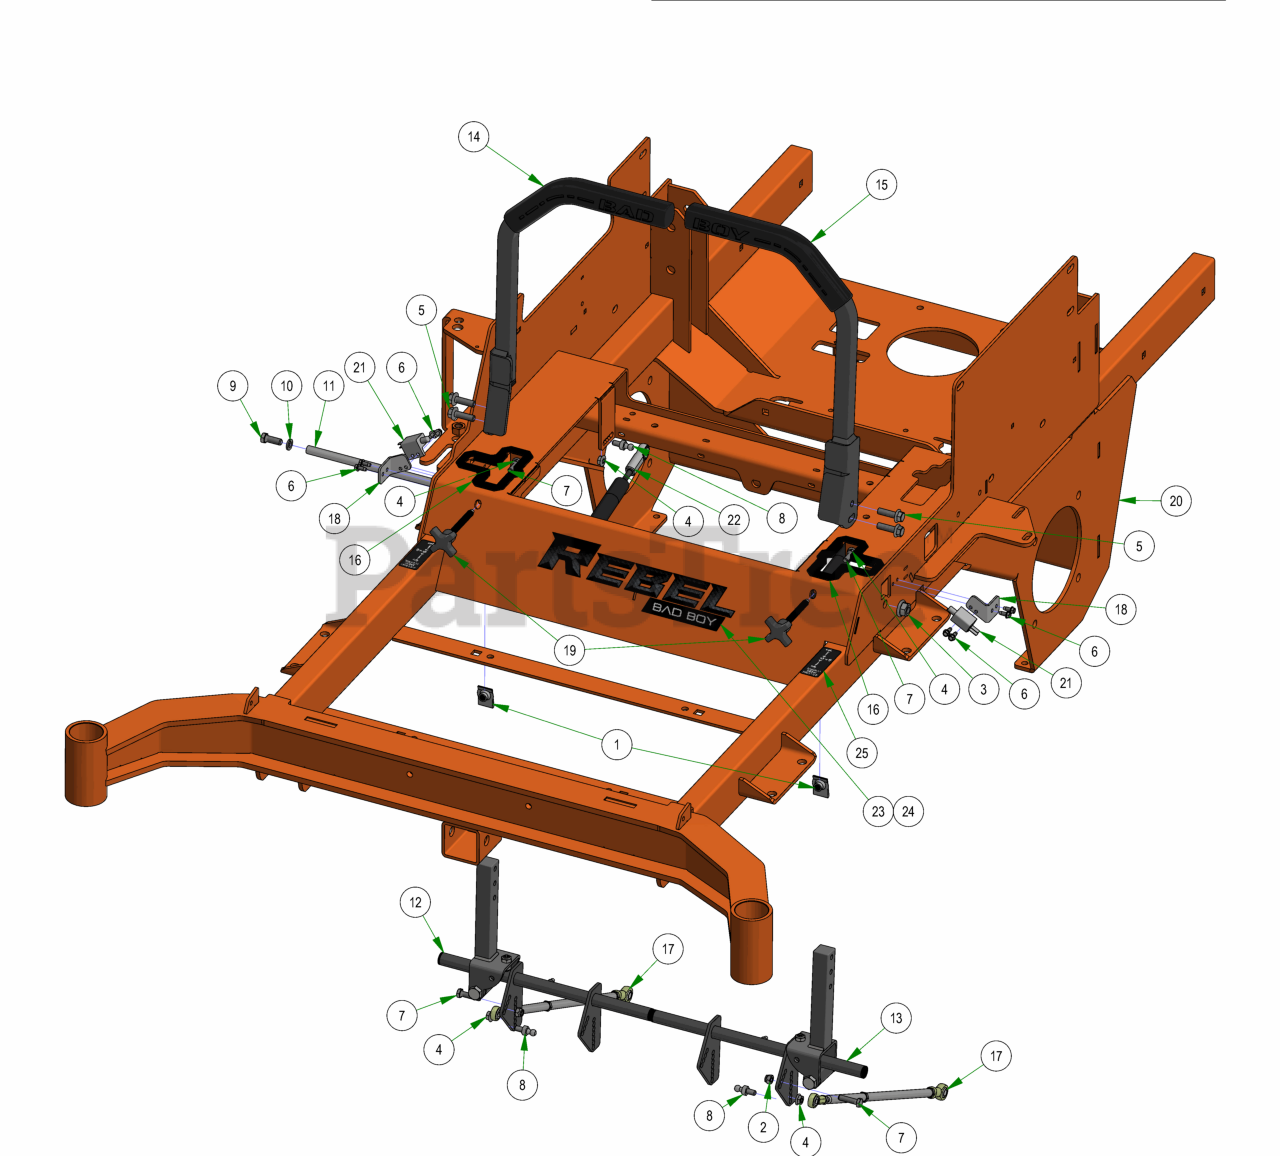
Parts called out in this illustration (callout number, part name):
1	Extruded Nut 3/8"-16 3/4" Hole Center With Patch
2	5/16-18 NYL INS L/N ZC
3	1/2-13 NYLON INSERT FLANGE LOCKNUT ZINC
4	5/16-18 HEX SERRATED FLANGE NUT HARD/ZINC
5	3/8-16 X 1 1/4 HEX WASHER UNSLOT MACHINE SCREW ZINC GR5
6	12-24 X 1/2 HEX WASHER UNLSOT F TCS ZINC
7	5/16-18 X 1-1/4 HEX C/S (GR.5) ZC
8	10mm Damper Ball Stud-Steering
9	3/8-16 X 1 GR 5 Hex Bolts Zinc
10	3/8 SPLIT LOCKWASHER ZINC
11	2019 Steering Actuator Rod
12	R Series Square Drive Arm Actuator RH Assembly
13	R Series Square Drive Arm Actuator LH Assembly
14	R Series Square Drive Arm RH Assembly
15	R Series Square Drive Arm LH Assembly
16	Snap-in Drive Arm Bushing
17	2024 Rebel Push Rod Assembly
18	2019 Arm Switch Bracket
19	Speed Limiting Knob 3/8-16X 3"
20	2023 Rebel Frame - Painted
21	Safety Switch
22	Steering Damper
23	Rebel back Plate & Front Decal
24	Rebel X back Plate & Front Decal
25	2018 LH/RH Steering Control Decal Roll
